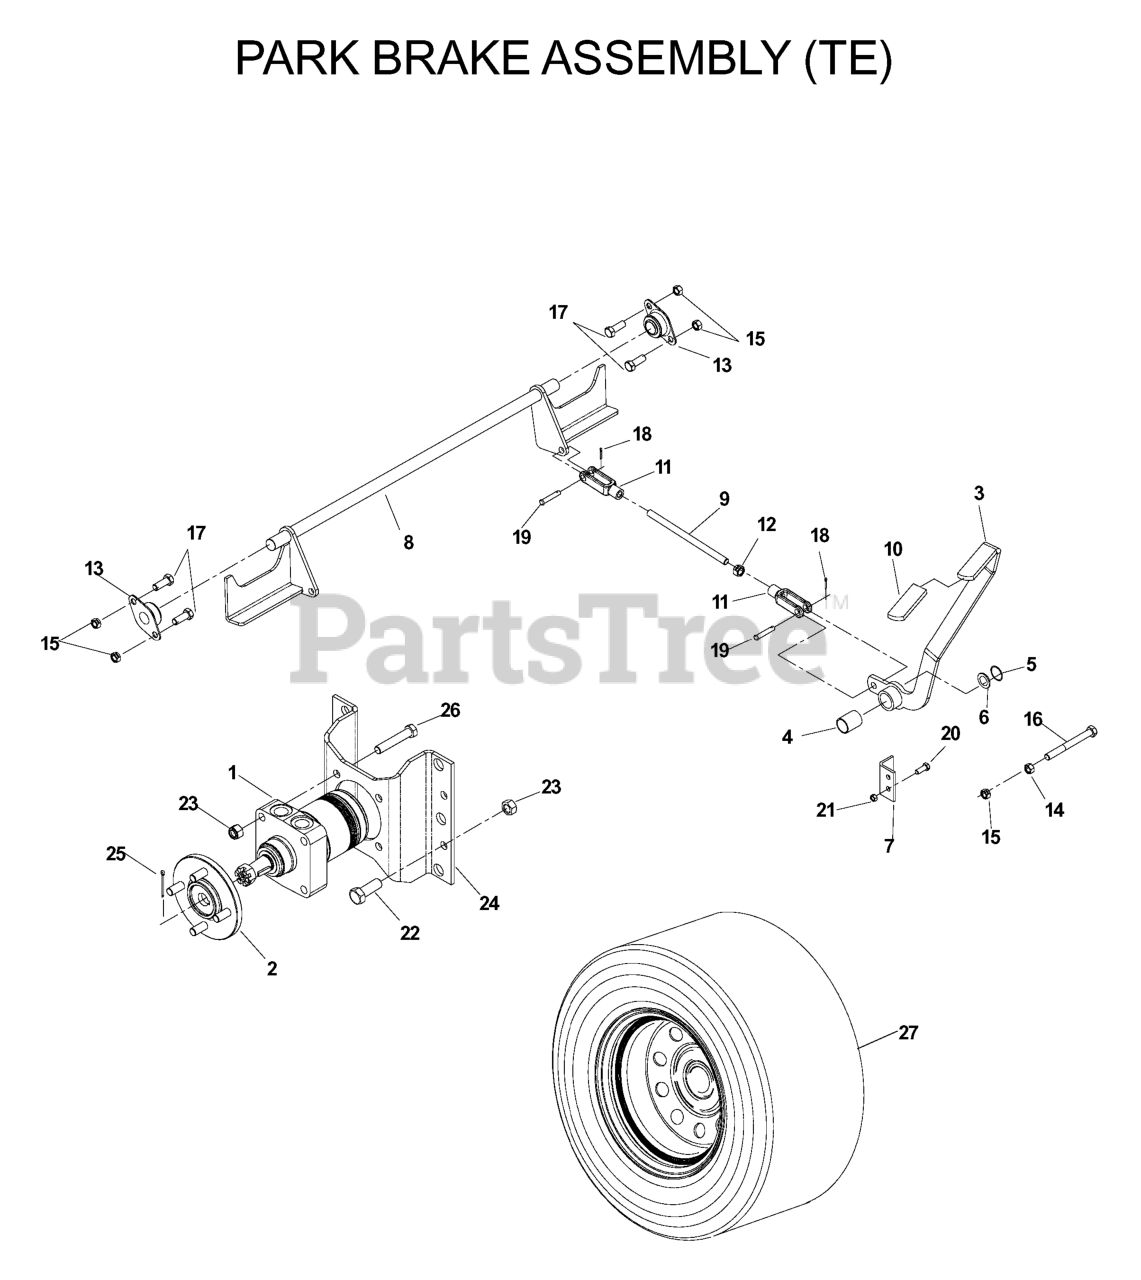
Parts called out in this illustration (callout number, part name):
1	WHEEL MOTOR
2	HUB.WHEEL.ZTR
3	BRAKE LEVER WLDMT
5	RETAINING RING, 7/8"
6	BSHG .875 X 1.375 X .074 ZD
8	BRAKE SHAFT WLDMT
10	GRIP, PARK BRAKE
11	YOKE-3/8-24 PLTD
13	FLANGE BEARING
14	NUT 3/8C WHIZ
15	NUT 3/8-16 NYLOC
16	HCS 3/8C X 2 1/2
17	HCS 3/8-16X1.GRD.5.ZD
18	RP_COTTER PIN 1/8 X 3/4
19	CLEVIS PIN 3/8 X 1 1/8
20	HCS 1/4C X 3/4 HCS
21	NUT.1/4-20.HEX.NYLOC.ZD
22	HCS 1/2C X 1 1/4 SERRATED HEAD
23	NUT 1/2-13 HEX NYLOC ZD
24	MOTOR STANDOFF, TE, BLK
25	COTTER PIN
26	HCS 1/2C X 2 3/4
27	TIRE WHEEL ASM 23X8.5-12
539107432	TIRE - 23X8.5-12
539109344	RIM - 12 X 7
539912234	VALVE STEM TR-412
